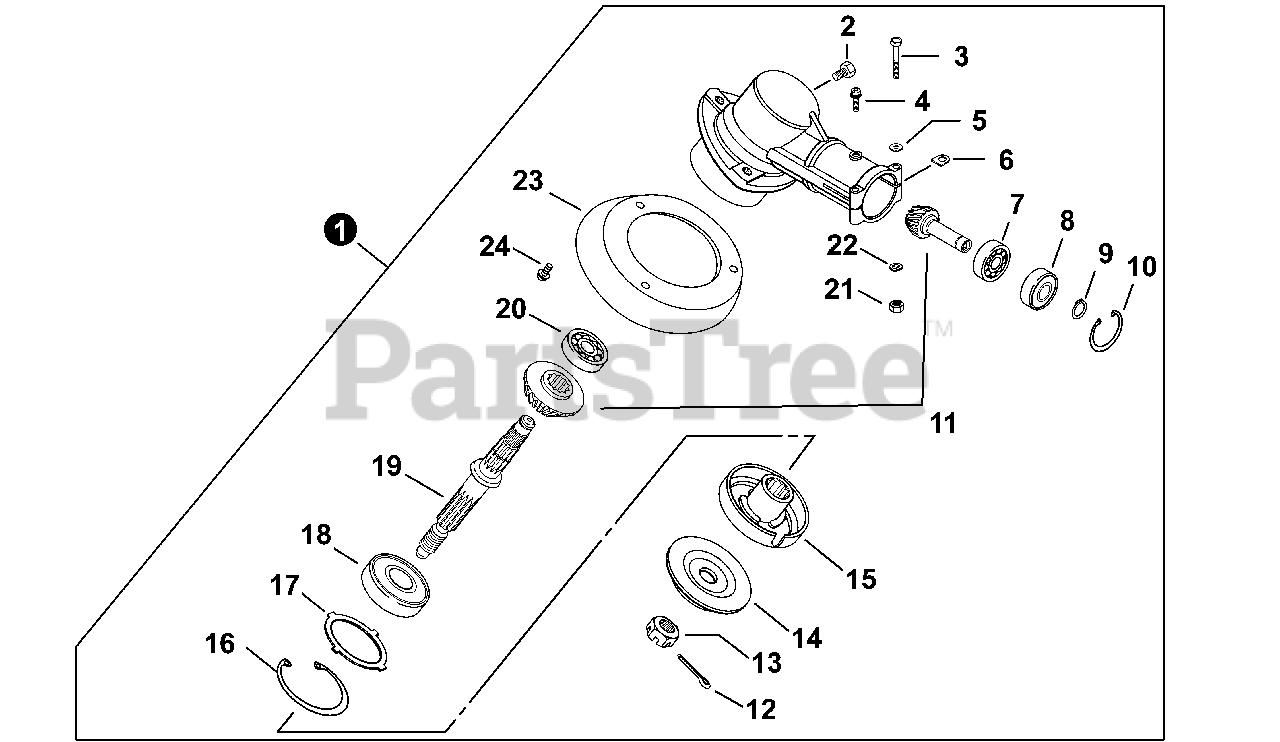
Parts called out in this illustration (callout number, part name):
1	GEAR CASE ASSY
2	BOLT M8×8
3	BOLT 5×35 SP
4	SCREW 5×10
5	WASHER, FLAT 5.5×10×0.8
6	D-WASHER
7	BEARING, BALL 6900
8	BEARING, BALL 6900Z
9	RING, SNAP Ø10
10	RING, SNAP Ø22
11	GEAR SET
12	PIN, COTTER 2×22
14	PLATE, ADAPTOR - LOWER
15	PLATE, ADAPTOR - UPPER
16	RING, SNAP Ø32
18	BEARING, BALL 6201
19	SHAFT, GEAR
20	BEARING, BALL 609
22	WASHER, FLAT 5.5×10×0.8
23	COVER, GEAR CASE
24	SCREW 5×20
